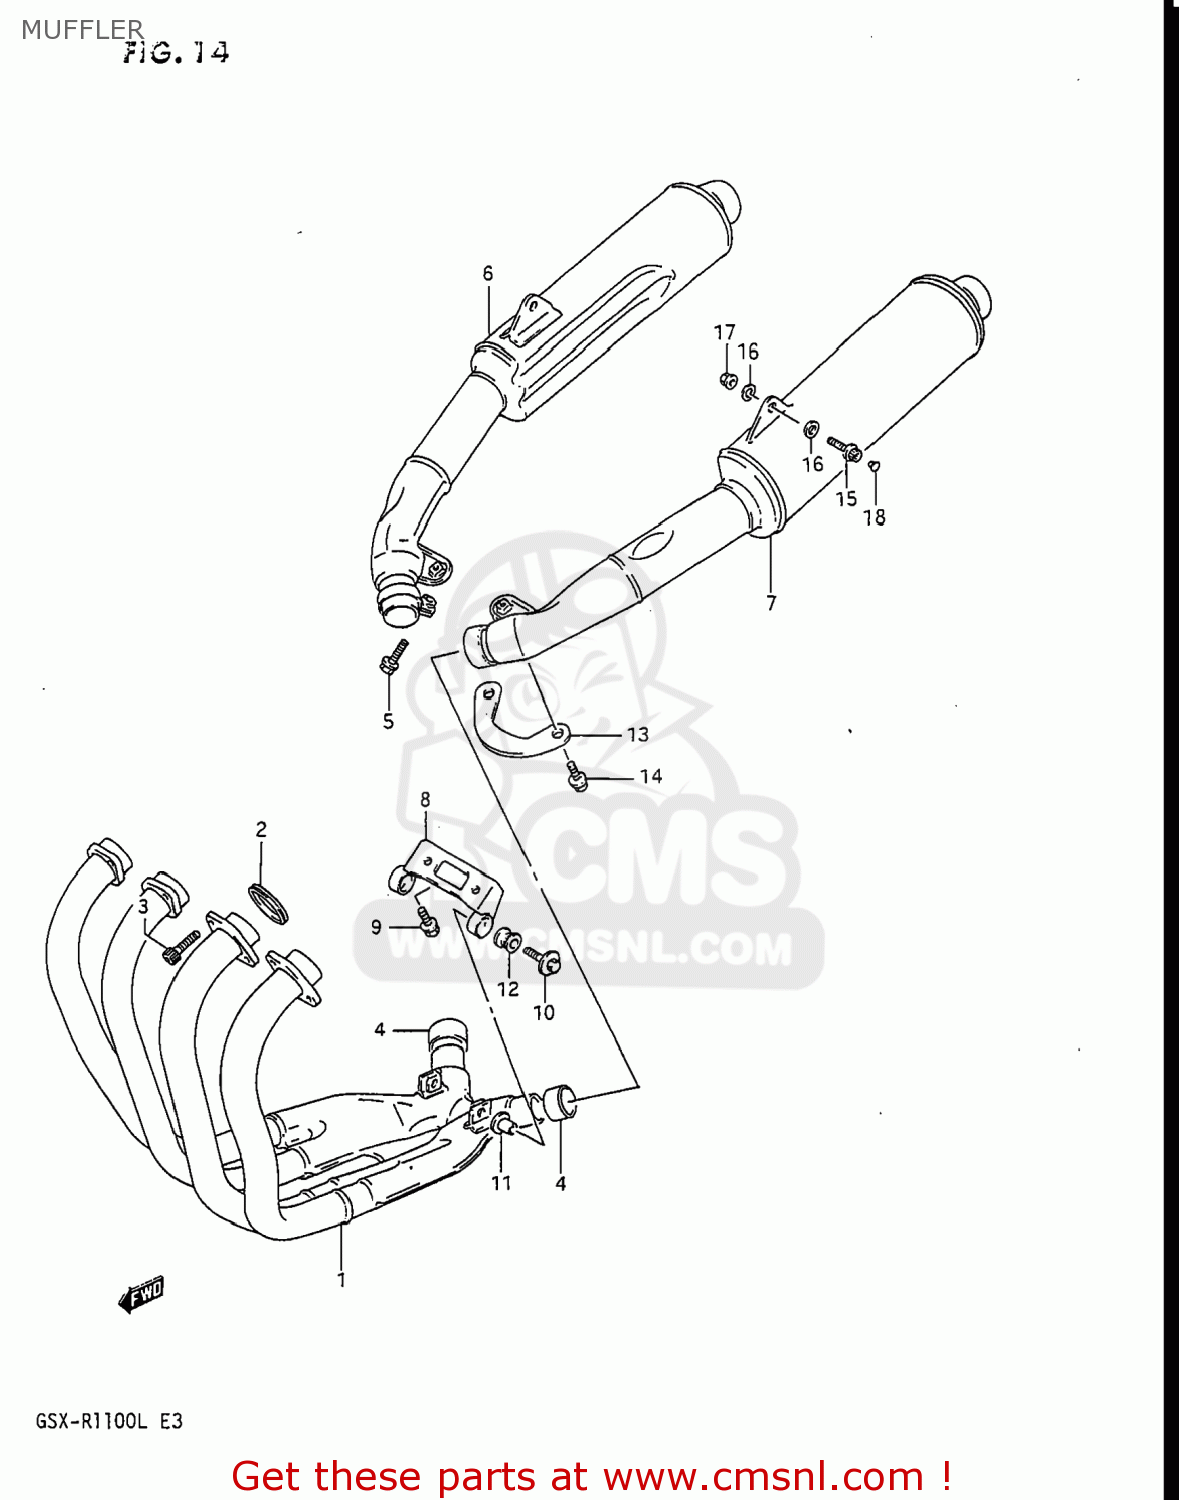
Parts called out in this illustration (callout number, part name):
1	PIPE,EXHAUST
2	GASKET,EXHAUST PIPE (NAS)
3	BOLT
4	CONNECTOR,MUFFLER
5	BOLT (8X40)
6	BODY,MUFFLER
7	BODY,MUFFLER
8	DAMPER,MUFFLER SUPPORT
9	BOLT(8X20)
10	BOLT(8X35)
11	SPACER(8.6X12X18.5)
12	CUSHION
13	PLATE,MUFFLER JOINT
14	BOLT
15	BOLT
16	WASHER (10.5X24X2.3)
17	NUT
18	CAP(OD:12)
